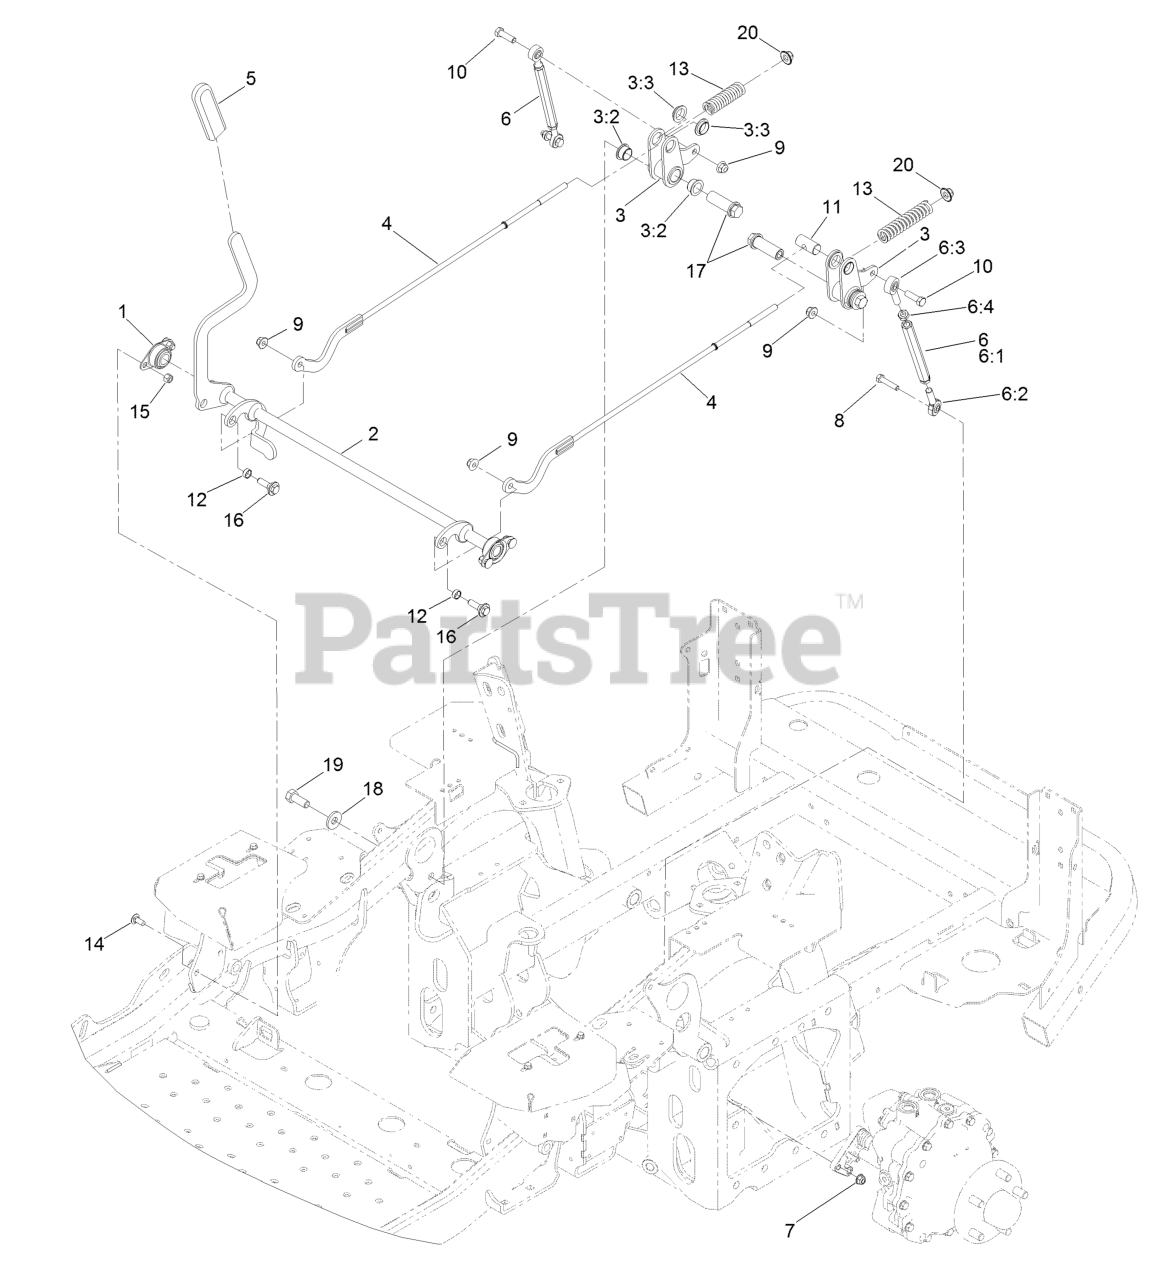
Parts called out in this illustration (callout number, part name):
1	Bearing-Flange, Side
2	Shaft-Brake
3	Brake Bellcrank ASM
3:2	Bushing-Flange
3:3	Bushing-Flange
4	Link-Brake, Upper
5	Grip-Lever
6	Turnbuckle ASM
6:1	Turnbuckle
6:2	Bearing-End, LH Rod
6:3	Balljoint
6:4	Nut-HJ
7	Nut-HF, NI
8	Screw-HH
9	Nut-HF, NI
10	Screw-HH
11	Pin-Trunion
12	Bearing-Sleeve
13	Spring-Compression
14	Screw-CARR
15	Nut-Lock, NI
16	Screw-Shoulder, HWH
17	Hub-Threaded
18	Washer-Spring
19	Screw-HH
20	Nut-Flange, NI
